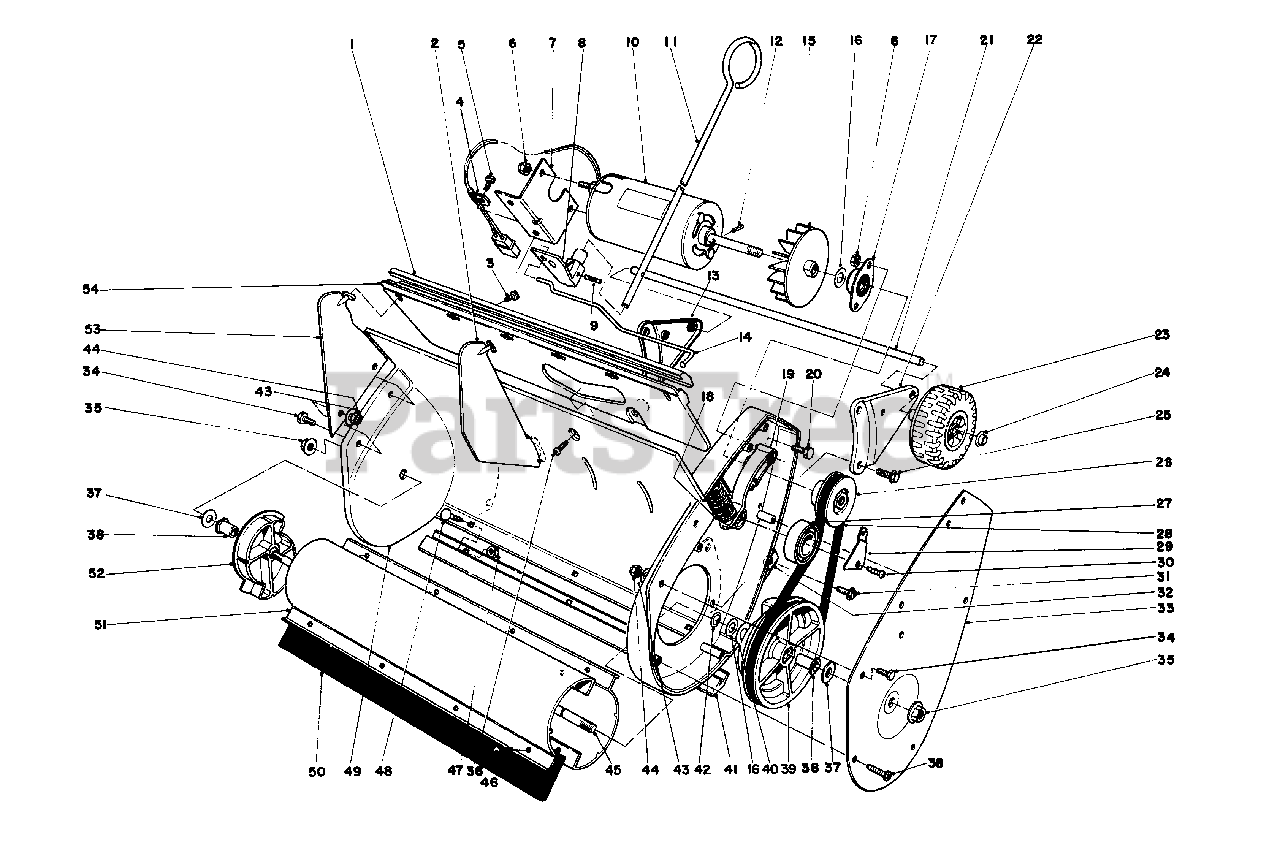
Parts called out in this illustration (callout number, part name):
1	Moulding
2	Vane-Inner
4	Insulated Closed Clip
7	Bracket-Mounting
8	Bracket-Vane Adjustment
9	Groove Pin
11	Rod-Vane Adjustment
12	Spring Pin
13	Wheel Bracket R.H.
14	Linkage Vane Adjustment
16	Thrust Washer
17	Side Flange Bearing
18	Idler Spring
19	Idler Arm
21	Axle Shaft
22	Wheel Bracket L.H.
24	Push Nut
25	Screw
26	Drive Pulley
27	Ball Bearing
28	Drive Belt
29	Retainer-Idler Pulley
32	Tinnerman Nut
33	Cover-Belt Case
36	Screw
37	Thrust Washer
38	Rotor Bushing
39	Pulley-Driven
42	Retaining Ring
43	Washer
45	Shaft-Rotor
46	Screw-Thread Forming
48	Carriage Bolt
50	Blade-Rotor
52	End Cap Rotor
53	Vane-Outer
54	Vane-Mount
